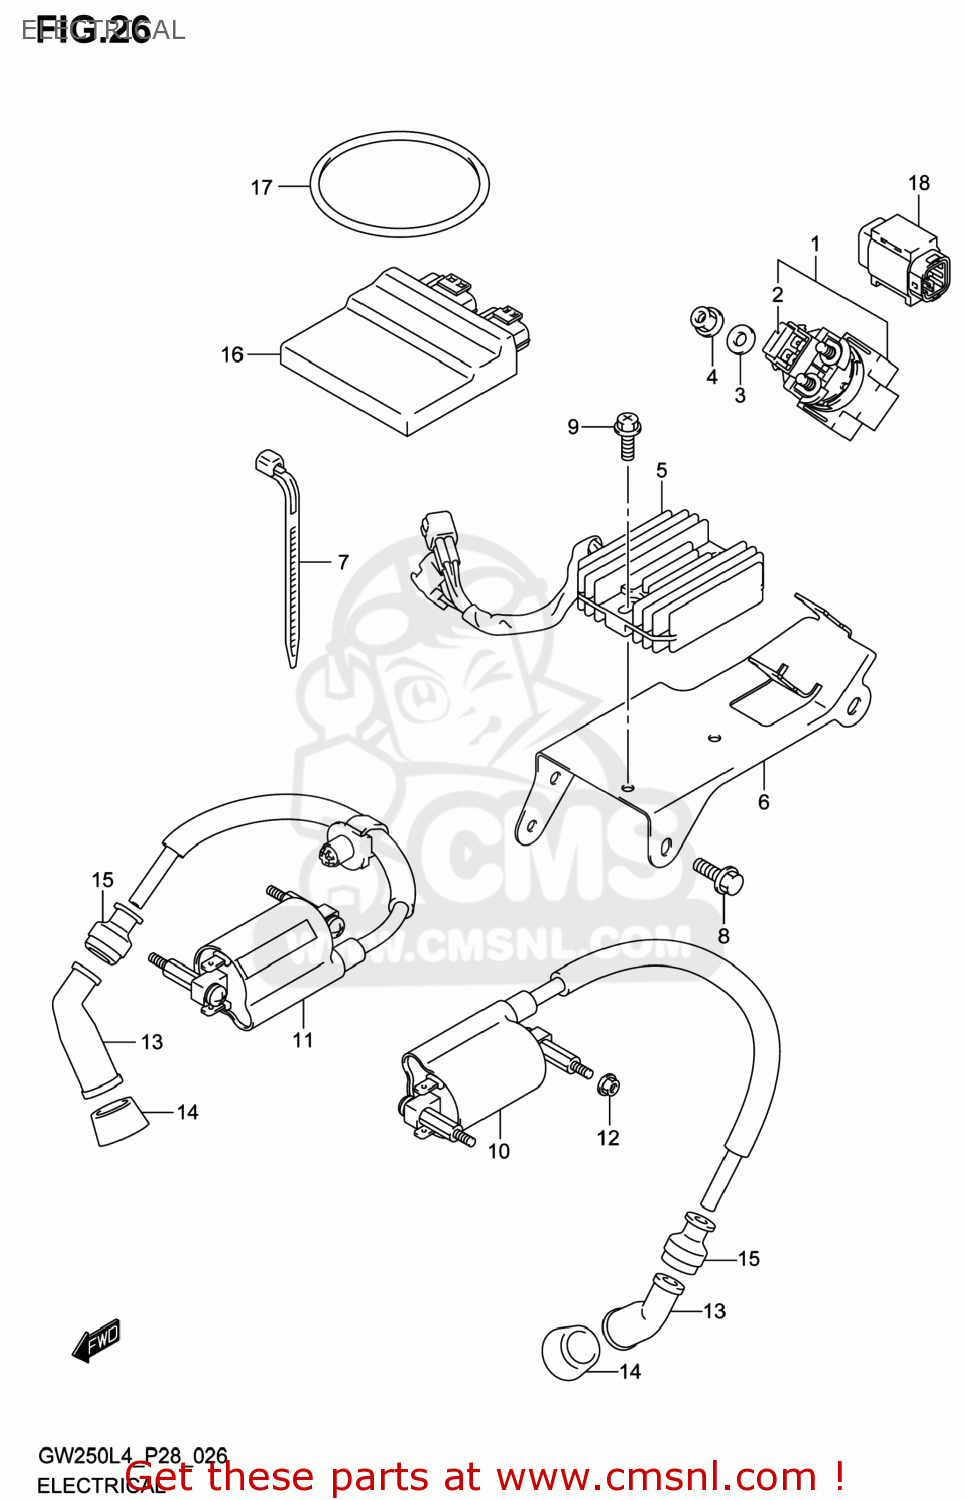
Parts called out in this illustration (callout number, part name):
1	RELAY ASSY,STARTING MOTOR
2	FUSE(30A)
3	WASHER(7.5X13X1)
4	NUT
5	RECTIFIER ASSY
6	BRACKET,RECT FTG
7	CLAMP,WIRING HARNESS
8	BOLT
9	SCREW
10	COIL ASSY,IGNITION
11	COIL ASSY,IGNITION NO.2
12	NUT
13	CAP,SPARK PLUG
14	SEAL,SPARK PLUG
15	SEAL,HIGH TENSION CORD
16	CONTROL UNIT,FI
17	BAND,FI CONTROL UNIT
18	SENSOR ASSY,FUEL CUT
